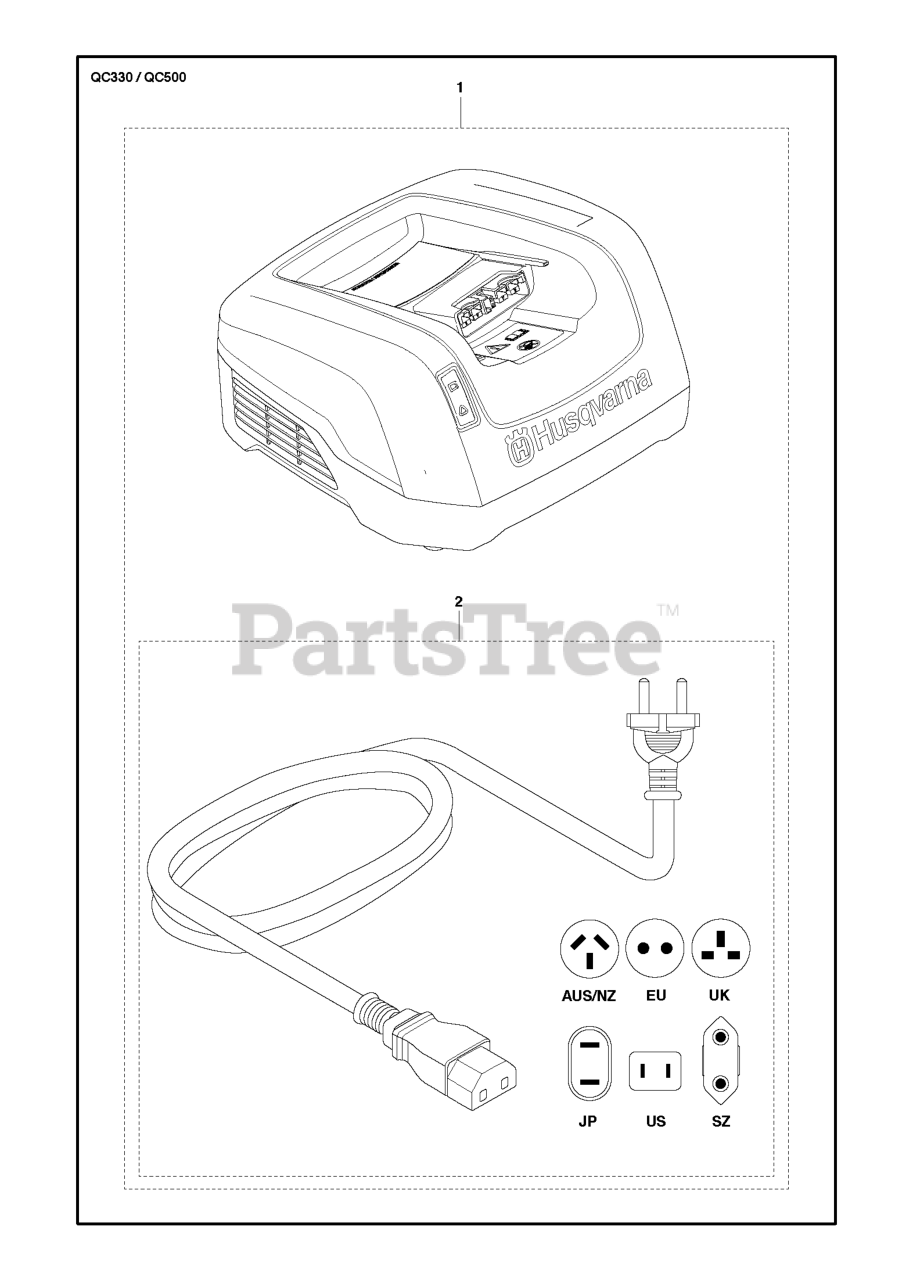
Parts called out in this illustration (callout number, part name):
1	BATTERY CHARGER QC330 330W QUI
1	QC500 BATTERY CHARGER
2	MAIN CABLE
2	CABLE
